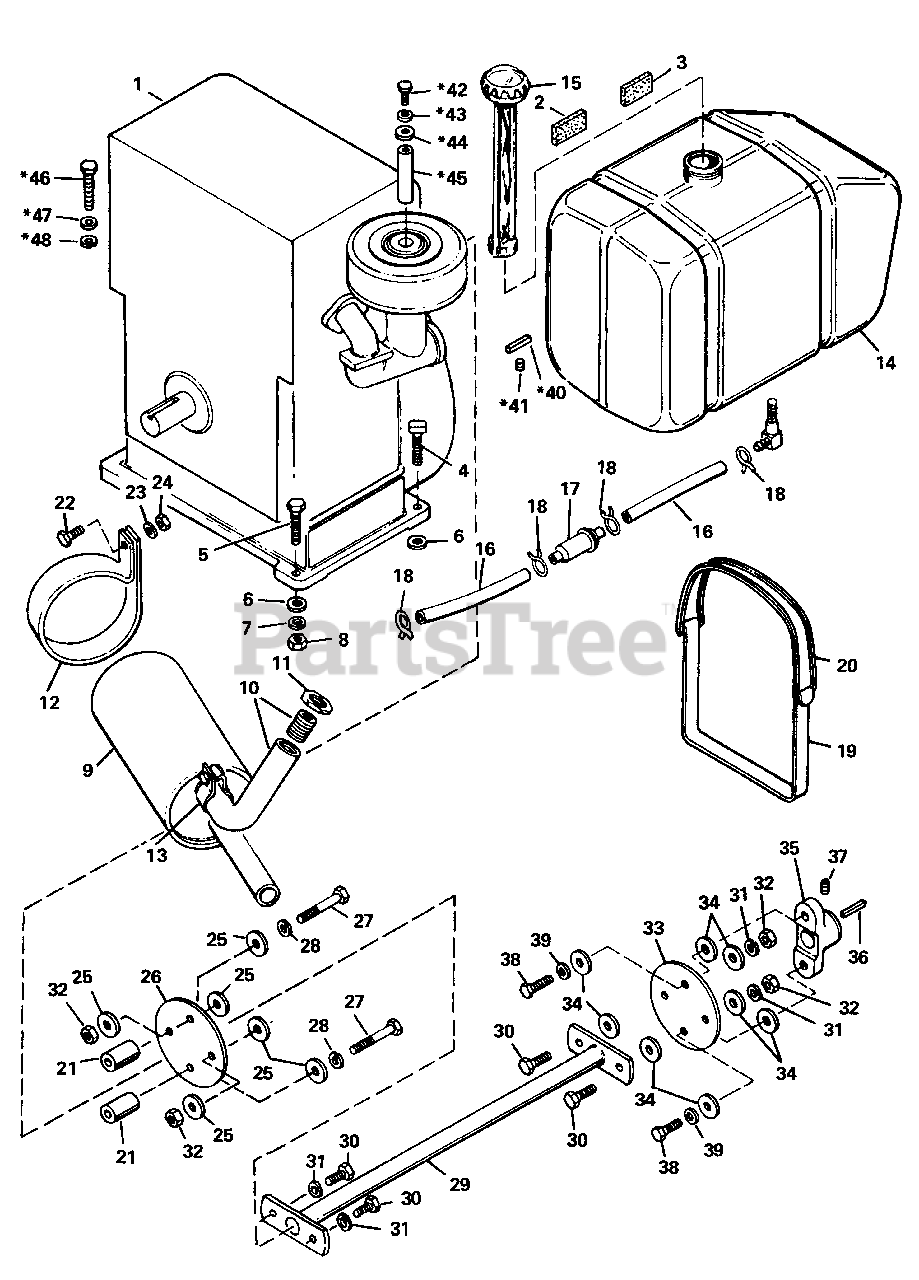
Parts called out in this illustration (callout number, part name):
2	PAD, Fuel Tank
3	GASKET, Felt
4	SCREW, Rec. Hd., 3/8-16 x 1-5/16" lg.
5	CAPSCREW, Hex, 3/8-16, x 1-1/2" lg.
6	WASHER, Plain, 3/8
7	LOCKWASHER, 3/8
8	NUT, full hex, 3/8-16
9	MUFFLER, Exhaust
10	ELBOW & NIPPLE ASSY.
12	STRAP, Muffler
13	CLAMP, Muffler
14	TANK, Fuel
15	CAP, Fuel tank
16	HOSE, Fuel
17	FILTER, Fuel
18	CLAMP, Fuel
19	STRAP, Tank
20	STRAP, Fuel tank
21	BEARING, Pivot black
22	CAPSCREW, Hex, 5/16 18 x 5/8" lg.
23	LOCKWASHER, 5/16
24	NUT, full hex, 5/16-18
25	WASHER, Special
27	CAPSCREW, Hex, 3/8-16 x 2-1/4" lg.
28	LOCK WASHER, 3/8
29	SHAFT ASSY., Drive
30	CAPSCREW, Hex, 3/8-16
31	LOCKWASHER, 3/8
32	NUT, Hex, full, 3/8-16
34	WASHER, Special
35	FLANGE, Drive shaft
36	SHAFT, Key Drive
37	SETSCREW, 3/8-24 x 3/8" lg.
38	CAPSCREW, Hex,3/8-16 x 1" lg.
39	LOCK WASHER, 3/8
40	KEY, Hi-Pro
41	SETSCREW, 5/16-18 X 3/8" lg.
42	CAPSCREW, Hex,1/4-20 x 5/8" lg.
43	LOCKWASHER, 1/4
44	WASHER, Plain, 1/4"
45	SPACER
46	CAPSCREW, Hex, 5/16-18 x 2" lg.
47	WASHER, Plain, 5/16
48	LOCKWASHER, 1/2
